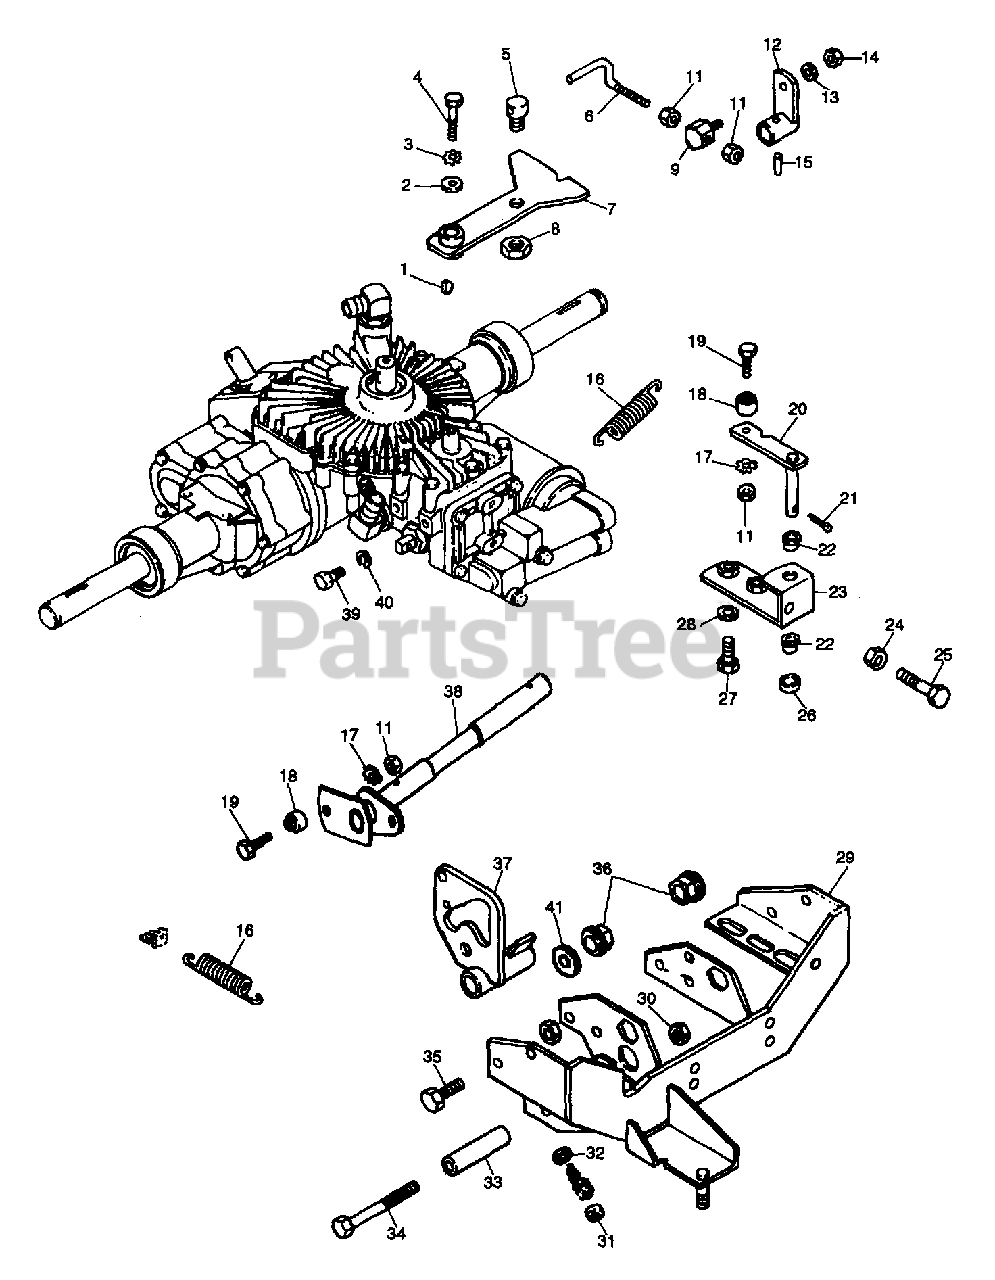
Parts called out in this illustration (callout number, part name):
1	KEY-WDRF .125X.500X.203 SAE 3
2	WSHR-FL-STL.312X.734X.065PL
3	WSHR-LK-EXT. 250 ID
4	BLT-HEX .25-20X1.50 PL GR5
5	ADAPTER
7	CONTROL ARM
8	NUT-LK-CTR .50-13
9	ROD PIVOT
11	NUT-LK-CTR .250-20 PL
12	ARM & HUB
13	WSHR-FL-STL .323X.625X.062 PL
14	NUT-LK .312-18 GR A PL
15	PIN-ROLL .125X.88
16	SG-TENS .080X.73X3.06 WLD 20
17	WSHR-LK .250X.047 LT PL
18	BRG BALL DBL .250X.638X.438
19	BLT-HEX .25-20X1.00 GR2
20	PIVOT ARM
21	PIN-COTR .12X1.0 PL
22	BSHG-FLG .500X.375X.500X.687
23	PIVOT BRACKET
24	NUT-LK-CTR .375-16 GR A PL
25	BLT-HEX .38-16X1.75 PL GR2
26	BSHG-SLV .377X.624X.235
27	BLT-HEX .38-16X.75 PL GR2
28	WSHR-FL-STL .382X.812X.062
29	TORQUE MOUNT
30	NUT-LK TOP .375-16 GR C YWZC
32	NUT-HEX .625-32 PL
33	SPACER .390X.750X2.761
34	BLT-HEX .38-16X3.50 PL GR5
35	BLT-HEX .38-16X.75 PL GR5
36	BSHG-FLG .625X.875X.750X1.19HX
38	CROSS SHAFT
39	BLT-HEX .31-18X.63 PL GR 2
40	WSHR-LK-EXT .313X.030 PL
41	WSHR-FL-STL .630X1.005X.062 PL
